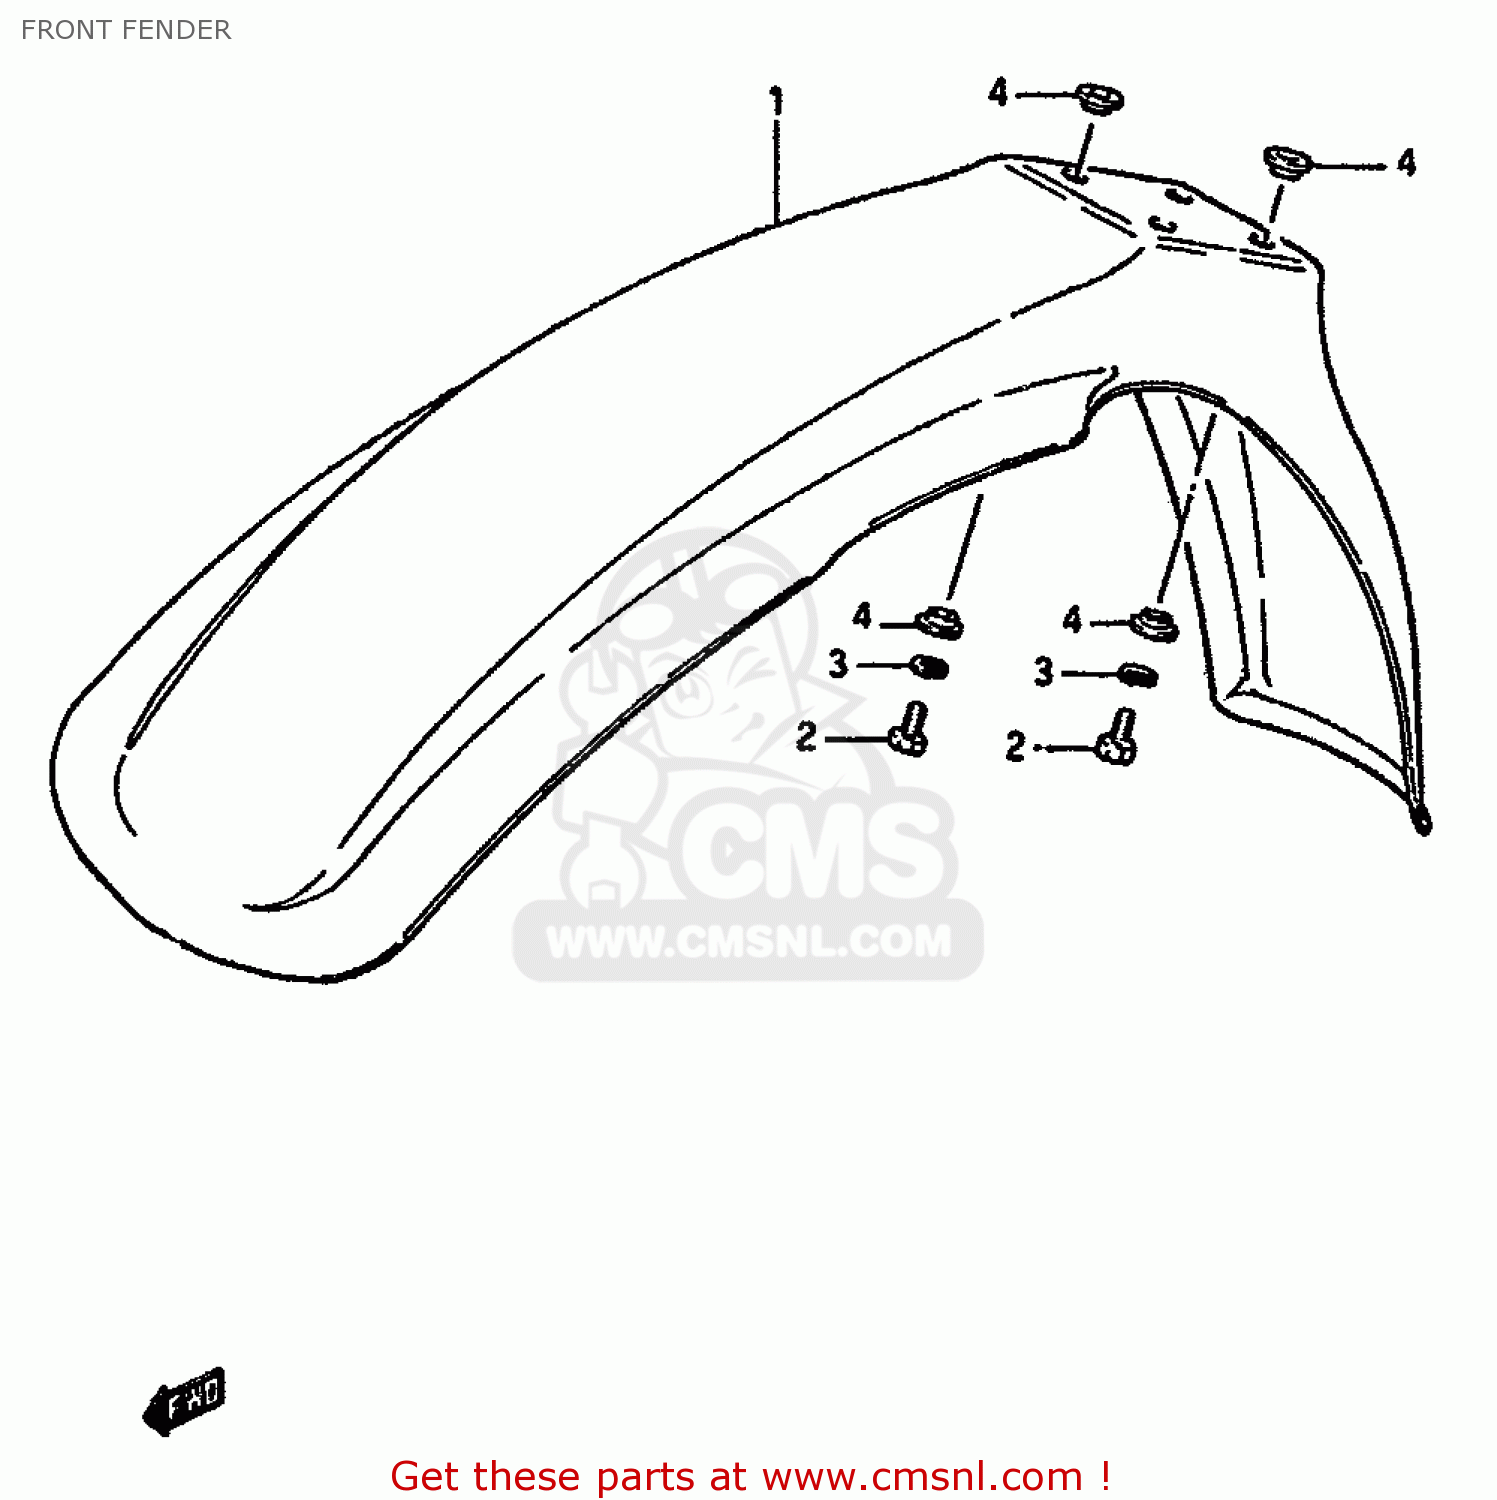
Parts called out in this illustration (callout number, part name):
1	FENDER,FR
2	BOLT
3	WASHER,LOCK
4	WASHER
